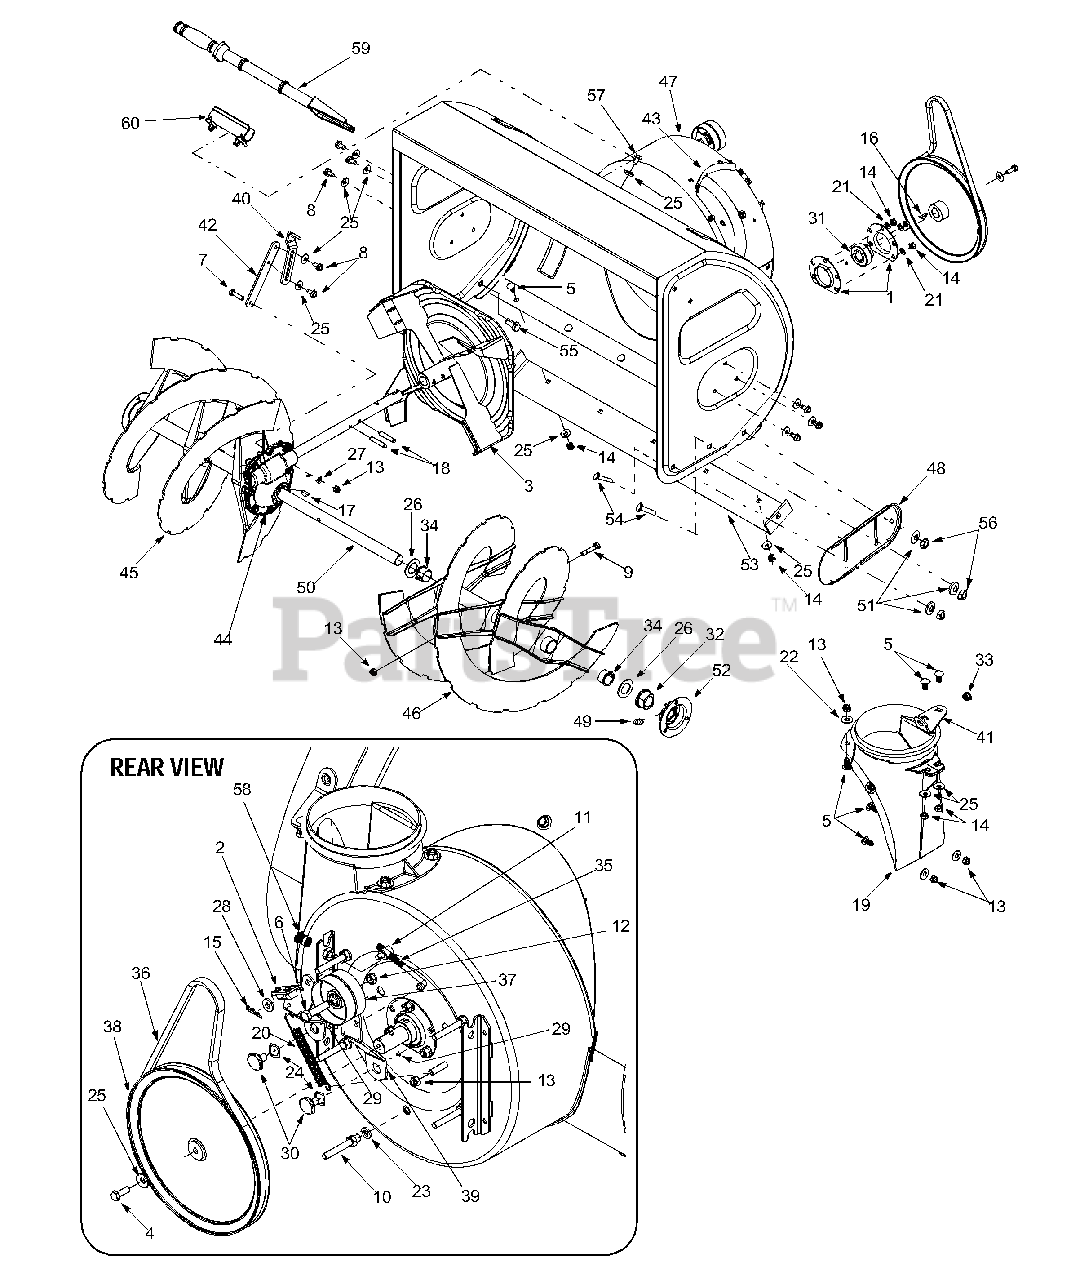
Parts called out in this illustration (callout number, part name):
1	Bearing Housing
2	Bracket Assembly: Auger Break
5	Carriage Bolt 5/16-18 x .750"
6	Hex Screw, Special 3/8-24 x 1.5"
7	Hex Screw 5/16-18 x 1.25"
8	Self-Tapp. Screw 5/16-18 x .625"
9	Shear Bolt 5/16-18 x 1.75"
11	Ferrule
12	Jam Nut 3/8-24
13	Hex Lock Nut 5/16-18
14	Hex Nut 5/16-18
15	Hairpin Clip
18	Spiral Pin
19	Chute Adapter
20	Extension Spring
21	Lock Washer
22	5/16 Washer
23	Lock Washer
24	Wave Washer
25	Beleville Washer
26	Flat Washer
27	Spring Washer
28	Flat Washer
30	Shoulder Screw
31	Self-Aligning Bearing
32	Flange Bearing w/ Flats
33	Plastic Bushing
34	Flange Bushing
35	Idler Rod: Auger
36	V-Belt
37	Flat Idler
49	Lube Fitting
50	Spiral Axle
51	Bell Washer
54	Carriage Screw
55	Carriage Bolt
56	Hex Nut 3/8-16
57	Screw, 5/16-18 x .75
58	Insert Nut, 3/8-16
59	Chute Clean-out Tool
60	Mount, Chute Clean-out Tool
